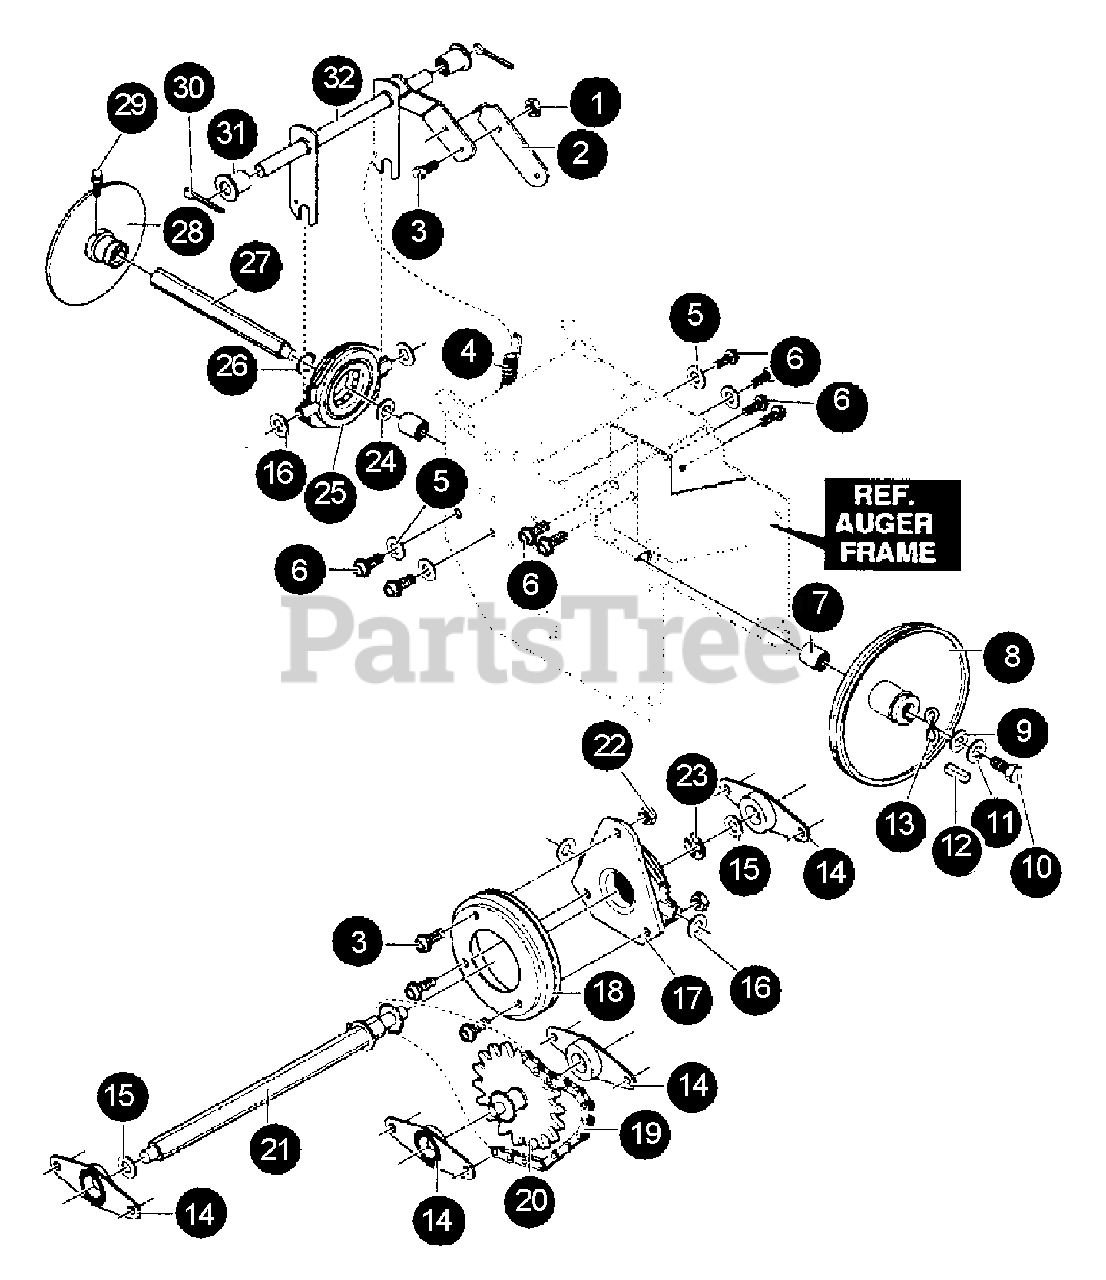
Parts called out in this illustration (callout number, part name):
1	NUT, 1/4"-20
2	LEVER, SPRING TRAC CL
3	SCREW 1/4"-20
4	SPRING, RETURN
5	WASHER
6	SCREW, 5/16-18×0.50 WAHHTAP
7	BEARING, BALL
8	PULLEY
9	WASHER, FLAT 0.281×1.00×0.063
10	SCREW 1/4 - 20×75 HHC
11	WASHER, REGSPTLK0.263×0.49×0.07
12	KEY, SQUARE 0.18SQX0.63LG
13	WASHER - SPRING
14	BEARING & RETAINER
15	WASHER
16	WASHER, FLAT
17	BEARING, TRUNION CLUTCH
18	FRICTION DISC WHEEL ASSY
19	CHAIN, ROLLER #42×40P
20	JACK ASSY #41-36T & 7T
21	HEX ASSY #40-8TW/PBRG
22	NUT
23	RING, RETEX
24	WASHER, FLAT 0.680×1.12×0.060Z
25	BEARING, TRUNION 1.25 ID
26	RING, RETEX
27	SHAFT, HEX TRACTION
28	DISC ASSY, FRICTION WHEEL
29	ZERK, GREASE 0.25-28×1.12LG
30	PIN - 1-1/4×1" -- COTTER
31	BEARING, FLANGE
32	LEVER ASSY, TRACTION CLUTCH
